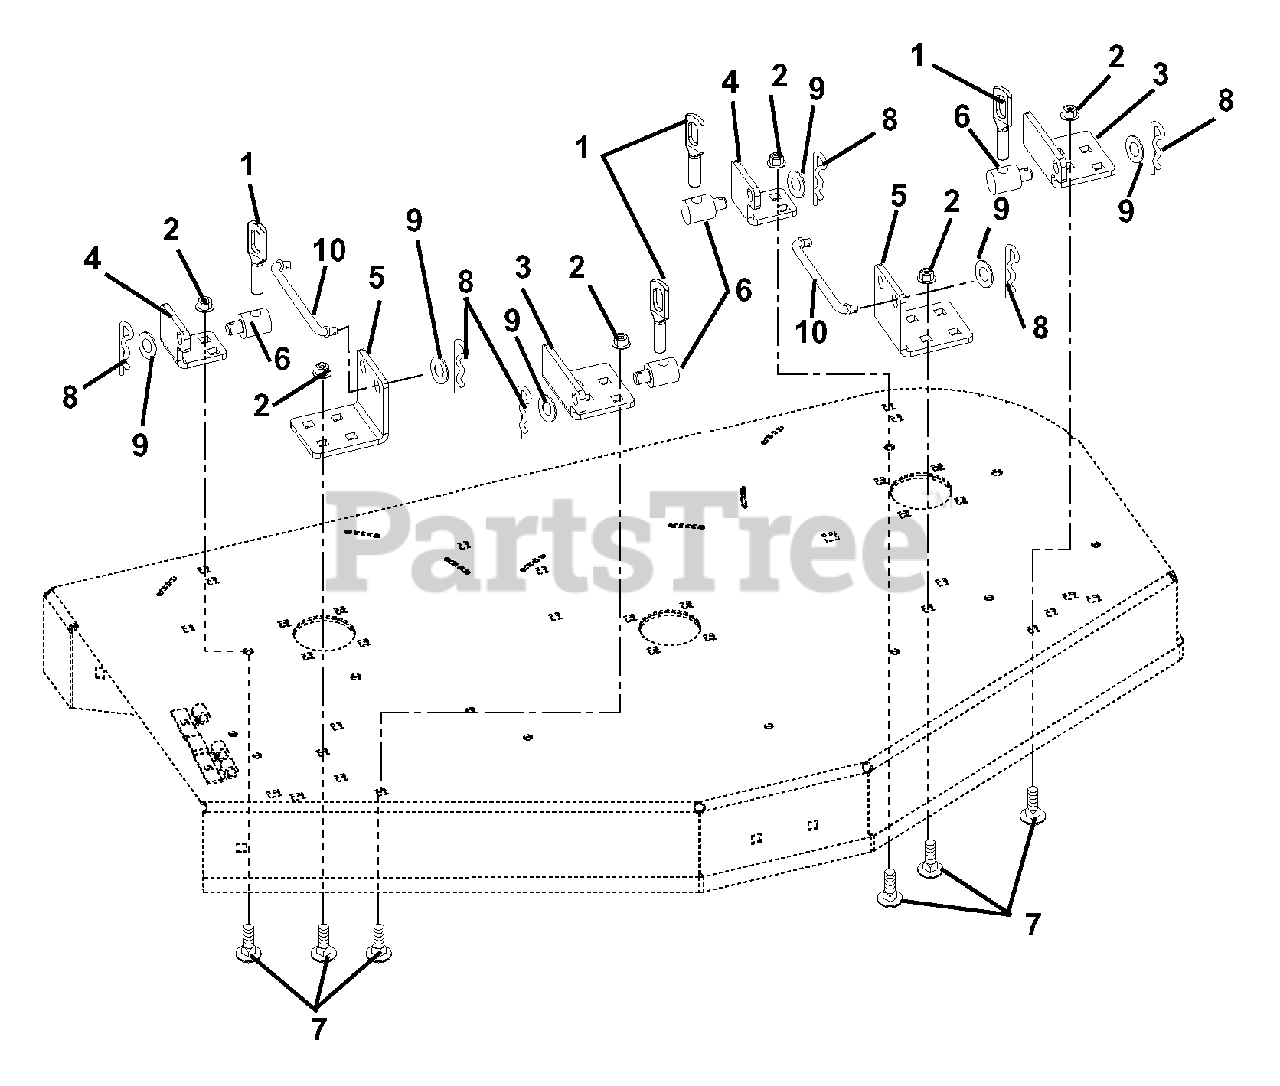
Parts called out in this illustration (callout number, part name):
1	DECK LINK
2	@NUT-LK-NYL-FLG .38-16 YWZC
3	BRACKET, MOUNT,FRONT
4	BRACKET, REAR MOUNT
5	BRACKET, STABILIZER
6	TRUNNION-.50
7	@BLT-RDHDSQNK .38-16X1.00 G5YZ
8	PIN, HAIR, EXT - #16 YWZC
9	WSHR-FL-STL.511X1.441X.125 YWZ
10	ROD,DRAG LINK
